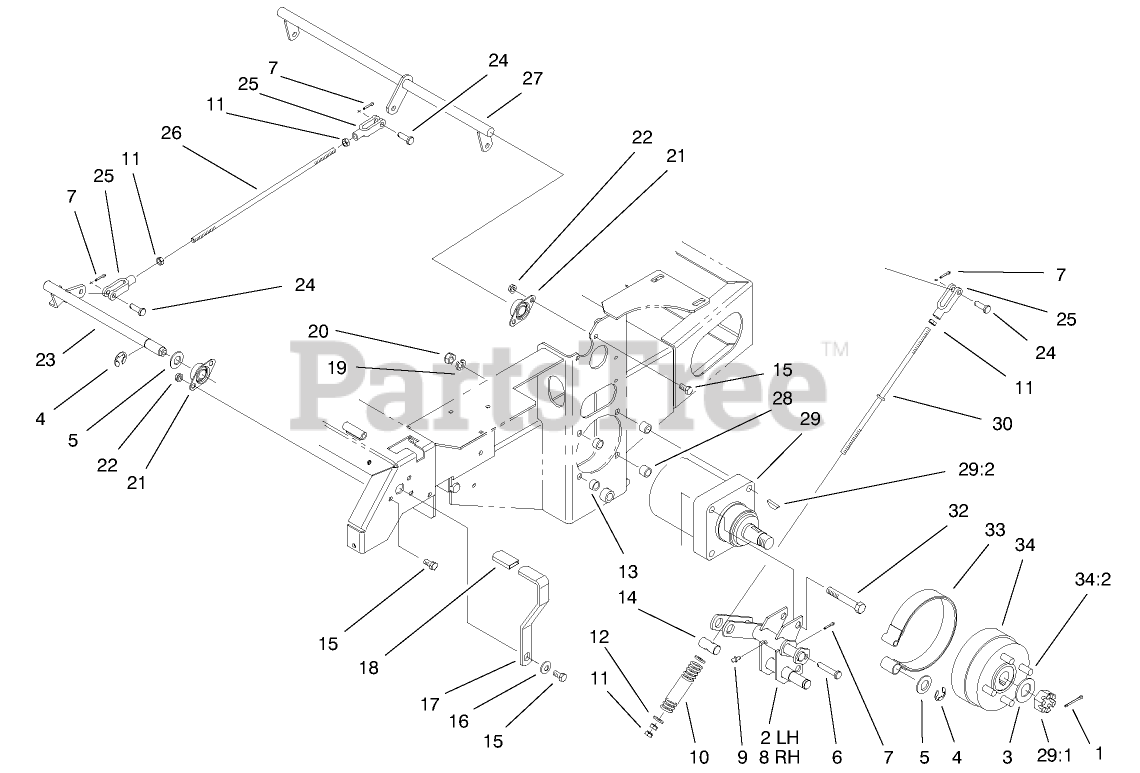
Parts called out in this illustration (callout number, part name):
1	Pin-Cotter
2	Bracket-Brake, LH
3	Spacer
4	Ring-Retaining
5	WASHER-FLAT
6	Pin-Clevis
7	PIN-COTTER
8	Bracket-Brake, RH
9	Fitting-Grease
10	Spring-Brake
11	NUT-HEX
12	WASHER-FLAT
13	Spacer
14	Pin-Trunion
15	SCREW-HH
16	Washer
17	Handle-Brake, Park
18	Grip-Brake Lever
19	WASHER-LOCK
20	NUT-HH
21	Bearing-Side Flange
22	NUT-HHF, WHIZ
23	Shaft-Brake
24	Pin-Clevis
25	Yoke-Brake Linkage
26	Linkage-Brake Handle
27	Brake Crank
28	Spacer
29	Motor-Wheel
29:1	Nut
29:2	Key-Woodruff
30	Rod-Brake
32	SCREW-HH
33	Band-Brake
34	Hub And Drum ASM
34:2	Stud-Wheel
